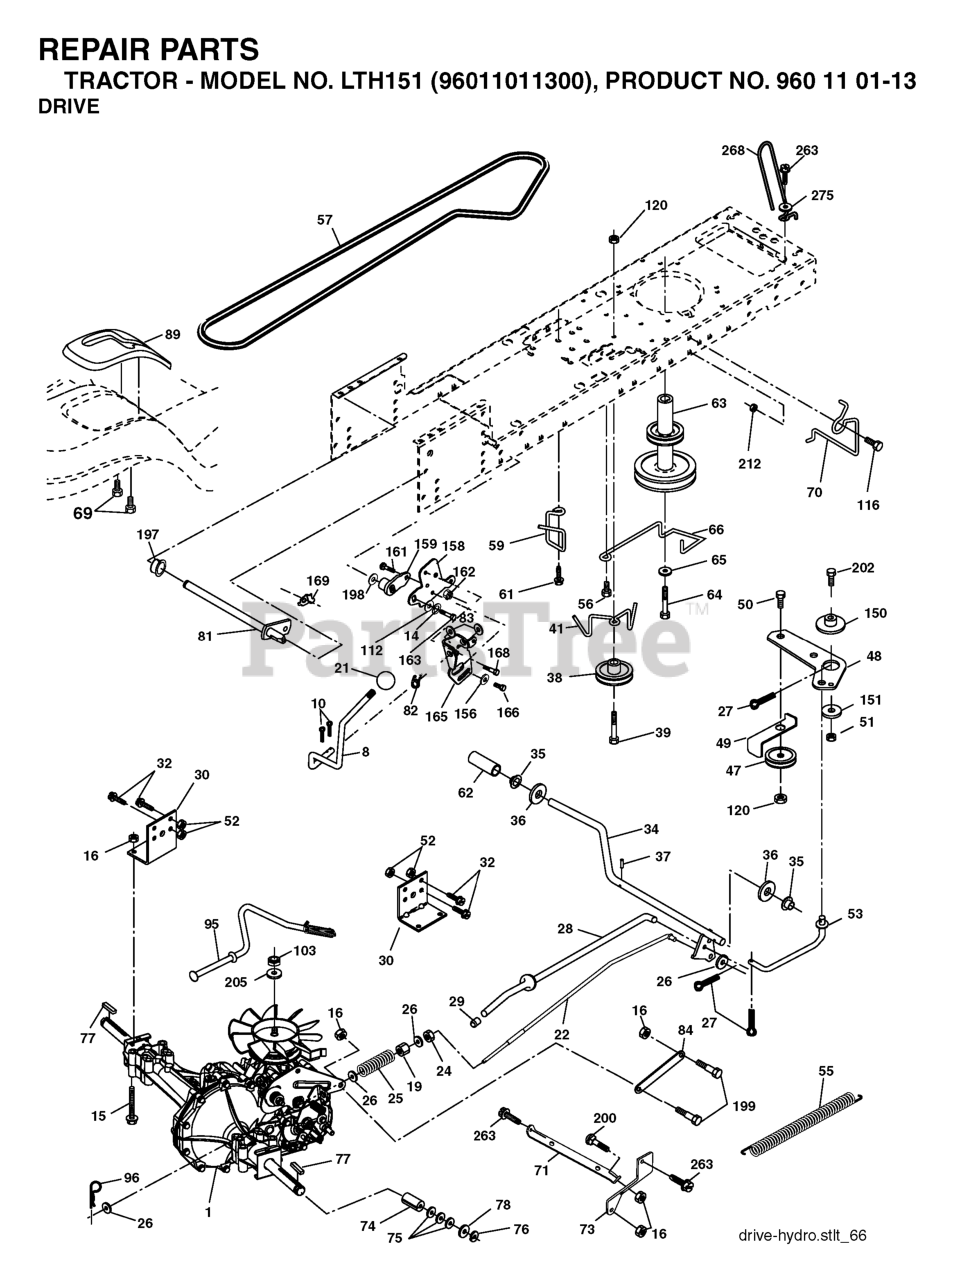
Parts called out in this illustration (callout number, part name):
8	ROD.SHIFT.FENDER.ADJ.STLT
10	PIN COTTER
14	LOCKWASHER
15	BOLT HEX 5/16-18 GR 5
16	NUT.71038.31-18.HEX.NYLOCK
19	NUT
21	KNOB.DUCKHEAD.1/2
22	ROD BRAKE HYDRO
24	NUT
25	SPRING ROD LT
26	WASHER
27	COTTER PIN
28	ROD, PARKING BRAKE
29	PLUNGER CAP
30	BRKT, MOUNT TRNSAXLE
32	BOLT
34	SHAFT, FOOT PEDAL
35	BEARING.NYLON
37	DRIVE PIN
38	PULLEY IDLER COMPOSITE
41	KEEPER, BELT IDLER
47	IDLER PULLEY
48	BELLCRANK, CLUTCH
49	RETAIN BELT
50	BOLT.3/8-16X1.50
52	LOCKNUT
53	LINK.CLUTCH.7.66.2005
55	SPRING, RETURN LT
56	SCREW.3/8-16
57	DRIVE BELT, LTH & YTH TRACTORS
59	KEEPER, BELT CENTER
61	SCREW 3/8-16X.875
62	PEDAL COVER T
63	ENGINE PULLEY
64	BOLT HEX 7/16-20X4-1/4"
65	LOCKWASHER
66	KEEPER BELT ENGINE
69	SCREW.HI-LO.CONSOLE
70	KEEPER BELT ENG
71	STRAP TORQUE LH HYDRO
73	STRAP TORQUE RH HYDRO
74	SPACER AXLE
77	SQUARE KEY
81	SHAFT ASM CROSS TAPERED
82	SHIFT SPRING
83	WASHER
84	LINK TRANSAXLE
89	CONSOLE, SHIFT, STL, AUTO GREY
95	CONTROL ASM. BYPASS HYDRO
96	RETAINER M
103	NUT.HEX.1/2-20
116	BOLT D
120	NUT LOCK FLG 3/8-16 UNC
150	SPACER, RETAINER
151	WASHER 12/32X2X10GA
156	WASHER.SRRTD.5/16
158	BRACKET
159	RB HUB.SHIFT
161	BOLT
162	NUT.CROWNLOCK.1/4
165	RP BRACKET
166	CAPSCREW.HXHD.FLG.5/16-18X.625
168	BOLT.SHOULDER.5/16-18X
169	PLATE.FASTENING.CROSS.SHAFT
197	NYLINER SNAP 5/8" ID
198	WASHER.NYL.7/8IDX.105"HYD CR
199	BOLT SHOULDER 5/16-18 UNC
205	WASHER
212	NUT
263	SCREW, 3/8-16X3/4
268	GUARD MUFFLER
275	WASHER
